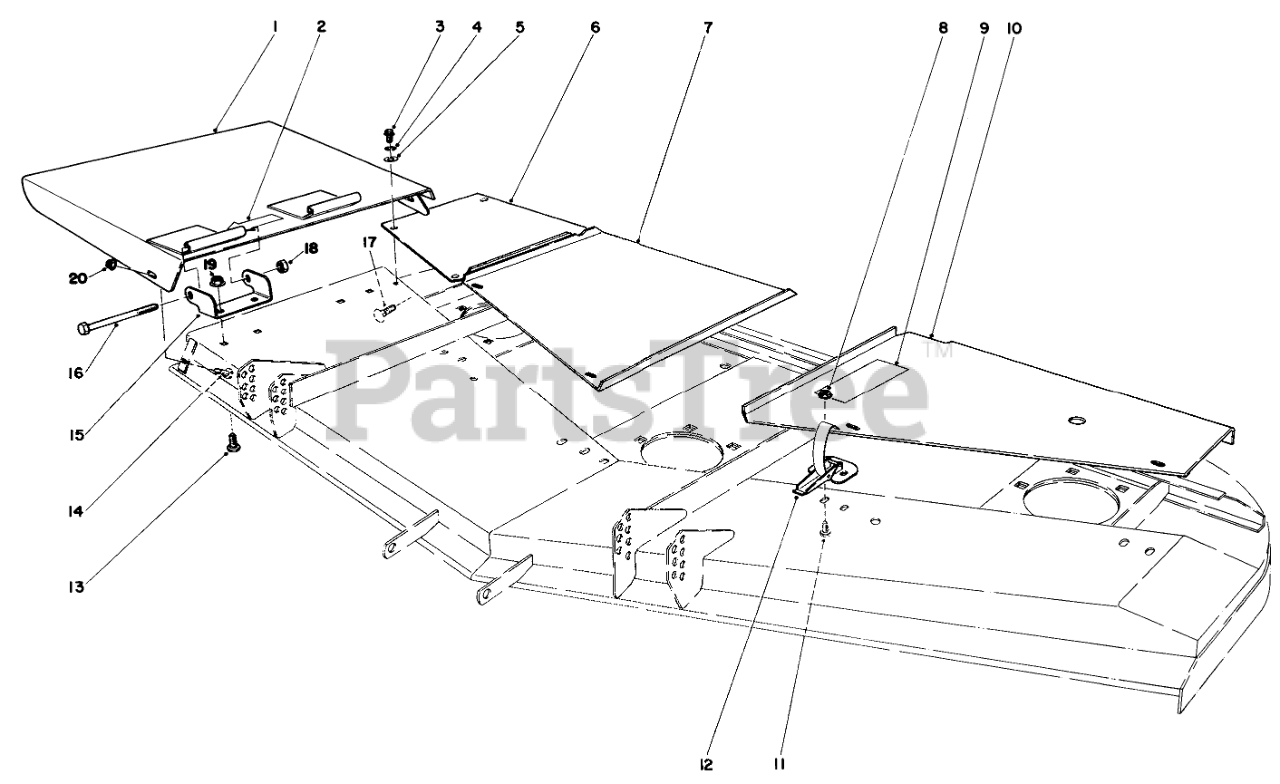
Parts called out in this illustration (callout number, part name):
1	Deflector
2	DECAL - BLADE LINE
3	SCREW THD 1/4 20 5/8
4	WASHER-LOCK
5	WASHER-FLAT
6	RH DECK COVER R
7	CTR DECK COVER R
8	NUT-LOCK, FLANGE
9	DECAL
10	Cover-Deck L.H.
11	SCREW-HWH
12	CLAMP-SLOTTED
13	SCREW-CARR
14	BOLT-CARR
15	HINGE BRKT
16	SCREW-HH
17	SCREW-CARR
18	NUT-HEX
19	NUT-HHF, WHIZ
20	NUT-HF
